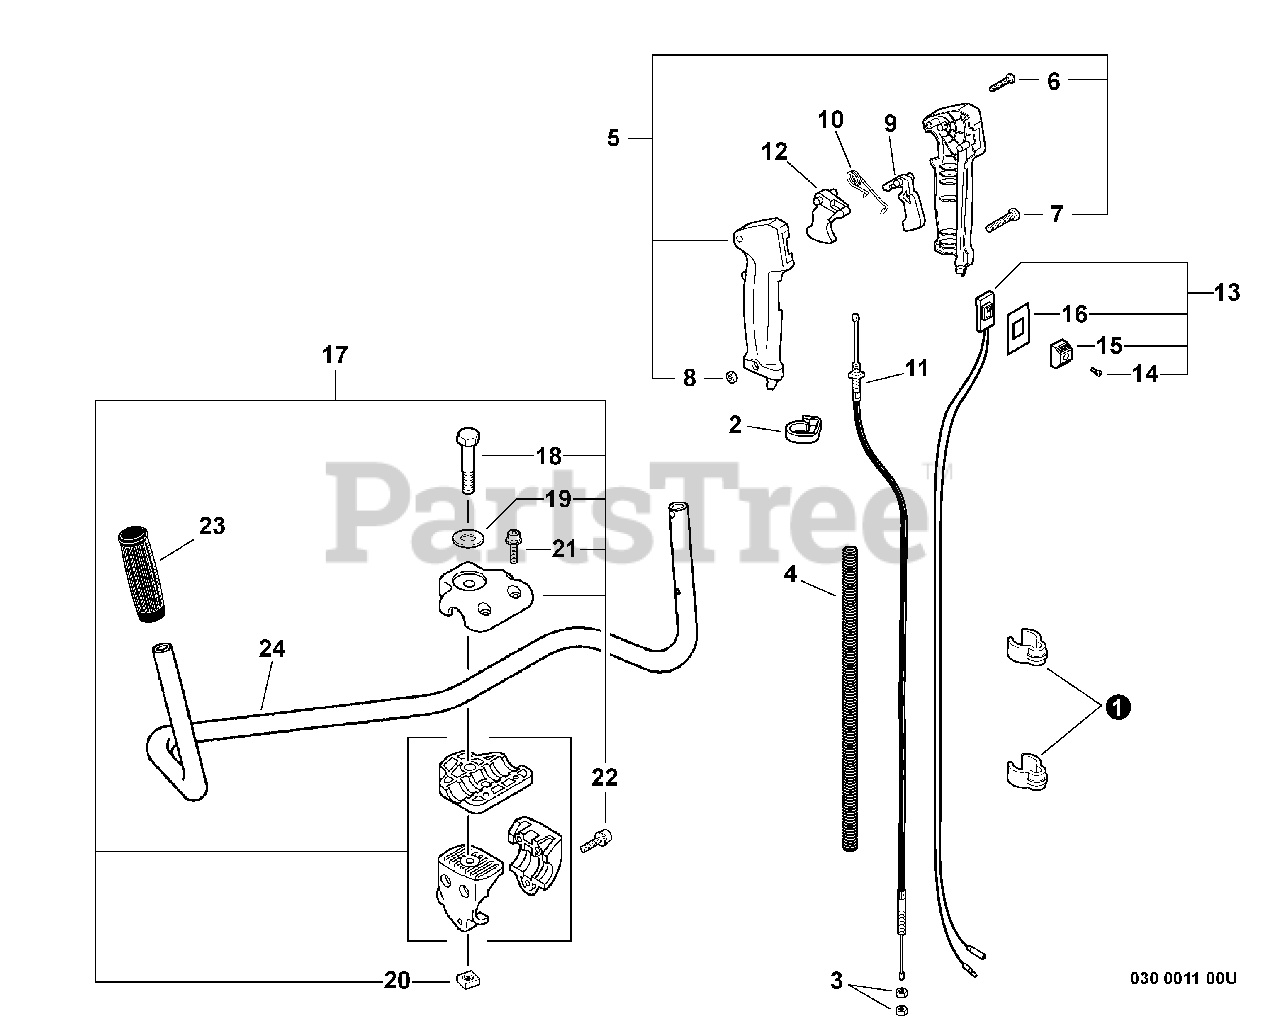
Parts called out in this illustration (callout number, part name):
1	CLIP, CABLE 25 MM
4	TUBE, FLEXIBLE 7×790
5	CONTROL HANDLE KIT
6	SCREW 3×25
7	SCREW 5×30
8	NUT M5
9	LOCKOUT, THROTTLE
10	SPRING, TORSION
11	CABLE, THROTTLE
12	TRIGGER, THROTTLE
13	SWITCH, ON-OFF
14	SCREW 3×10
15	KNOB, SWITCH - ORANGE
16	LABEL, SWITCH
17	BRACKET KIT, HANDLEBAR
18	BOLT 8×55
19	WASHER 8
20	NUT 8×1.25
21	BOLT 5×20
22	BOLT 5×30
23	GRIP, HANDLE
24	HANDLEBAR
